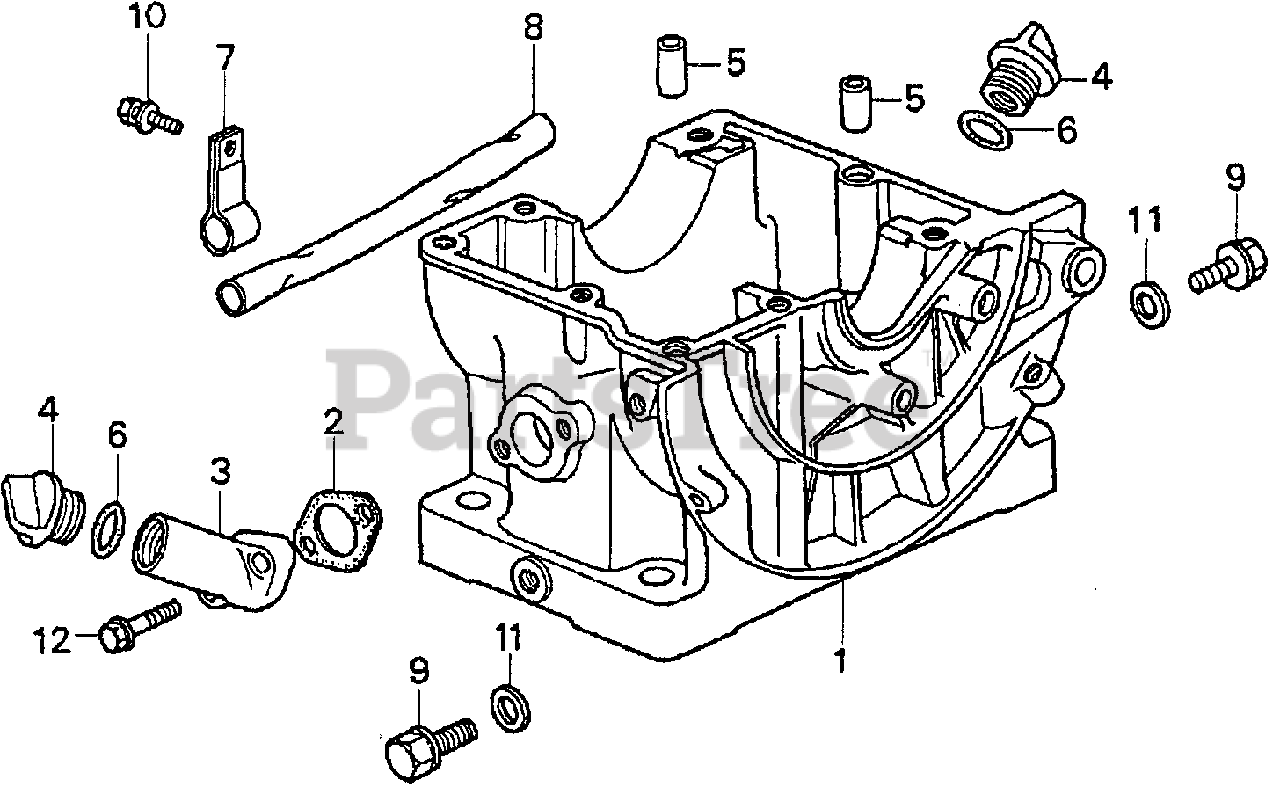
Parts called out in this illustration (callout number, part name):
2	GASKET, OIL PAN
4	CAP, OIL (YELLOW)
5	PIN, KNOCK (8.5X11) (NOT AVAILABLE)
6	O-RING (26X2.7)
7	CLIP, WIRE
8	TUBE, WIRE
9	BOLT, DRAIN PLUG (12MM)
10	BOLT-WASHER (8X12)
11	WASHER, DRAIN PLUG (12MM)
12	BOLT, FLANGE (6X32)
